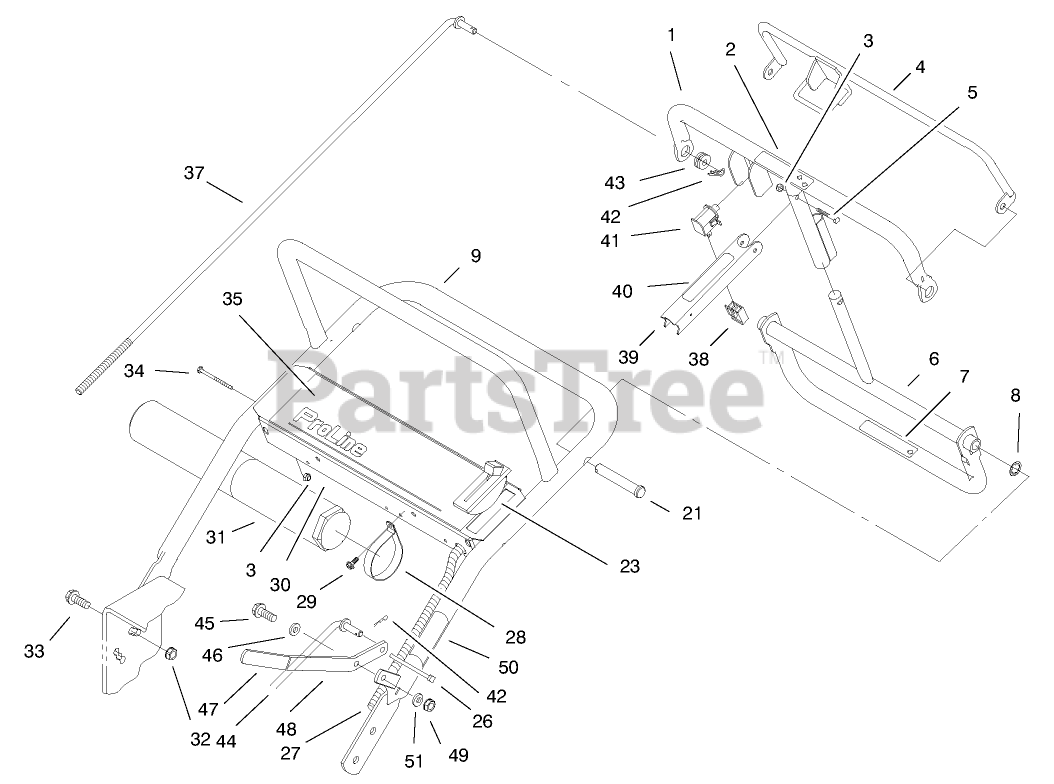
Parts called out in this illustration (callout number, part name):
1	Control Bar
2	DECAL
3	NUT-LOCK, NI
4	Bail ASM
5	SCREW-SHH
6	Pivot-Control
7	DECAL
8	NUT-PUSH-ON, CIRCULAR
9	Upper Handle ASM
21	PIN-CLEVIS
23	Throttle Control
26	TIE-CABLE
27	Wire Harness-Kawasaki
28	CLAMP-R
29	SCREW-HWHTF
30	Panel-Control
31	TUBE-MANUAL
32	NUT-HF
33	SCREW-HHF
34	SCREW-SHH
35	Decal-Panel
37	Rod-Control
38	CONNECTOR-BODY
39	Lever-Parking Brake
40	Decal-Parking Brake
41	SWITCH
42	PIN-COTTER
43	GROMMET-RUBBER
44	Linkage-Blade Drive
45	SCREW-SHOULDER, HWH
46	WASHER-THRUST
47	Grip
48	Lever-Blade Engagement
49	NUT-HEX
50	Decal-Blade Engagement
51	WASHER-FLAT
